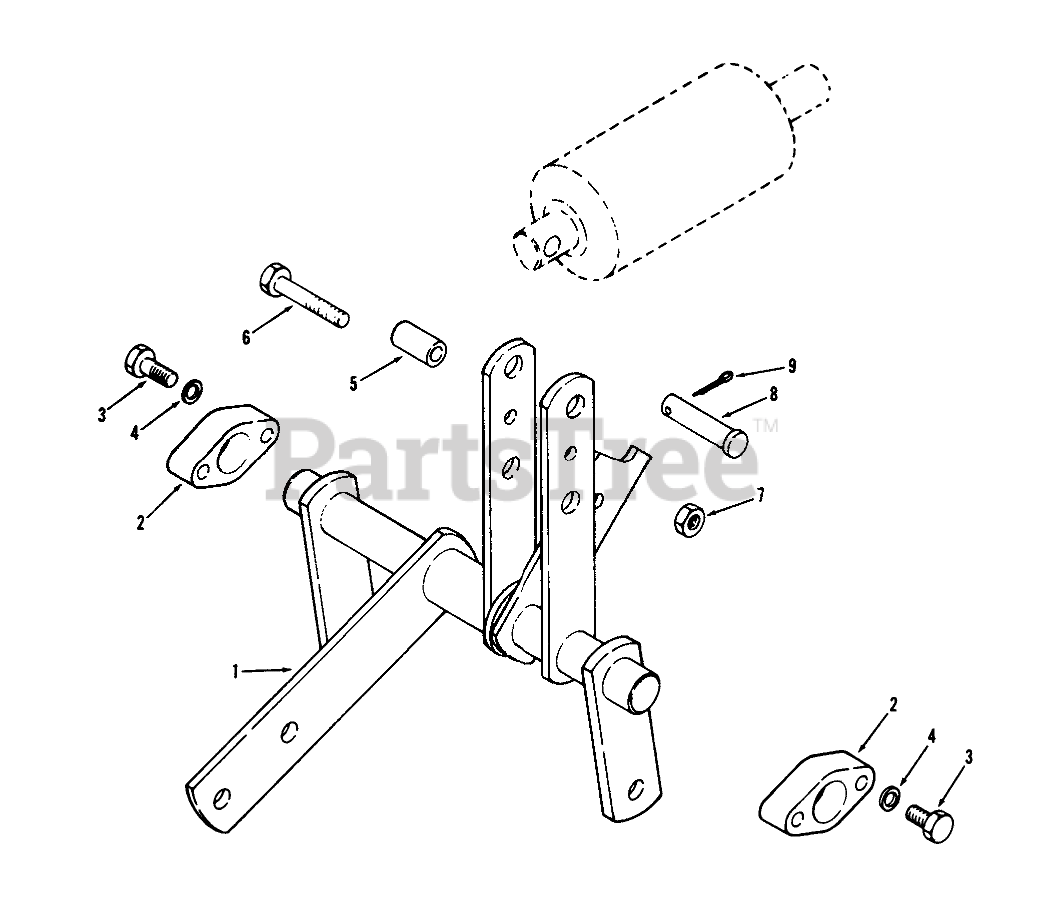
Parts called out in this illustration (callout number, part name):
1	Assy-Lift Bellcrank
2	BLOCK R
3	BOLT
4	LOCKWASHER
5	Spacer
6	Bolt
7	NUT
8	PIN CLEVIS .50 DIA
